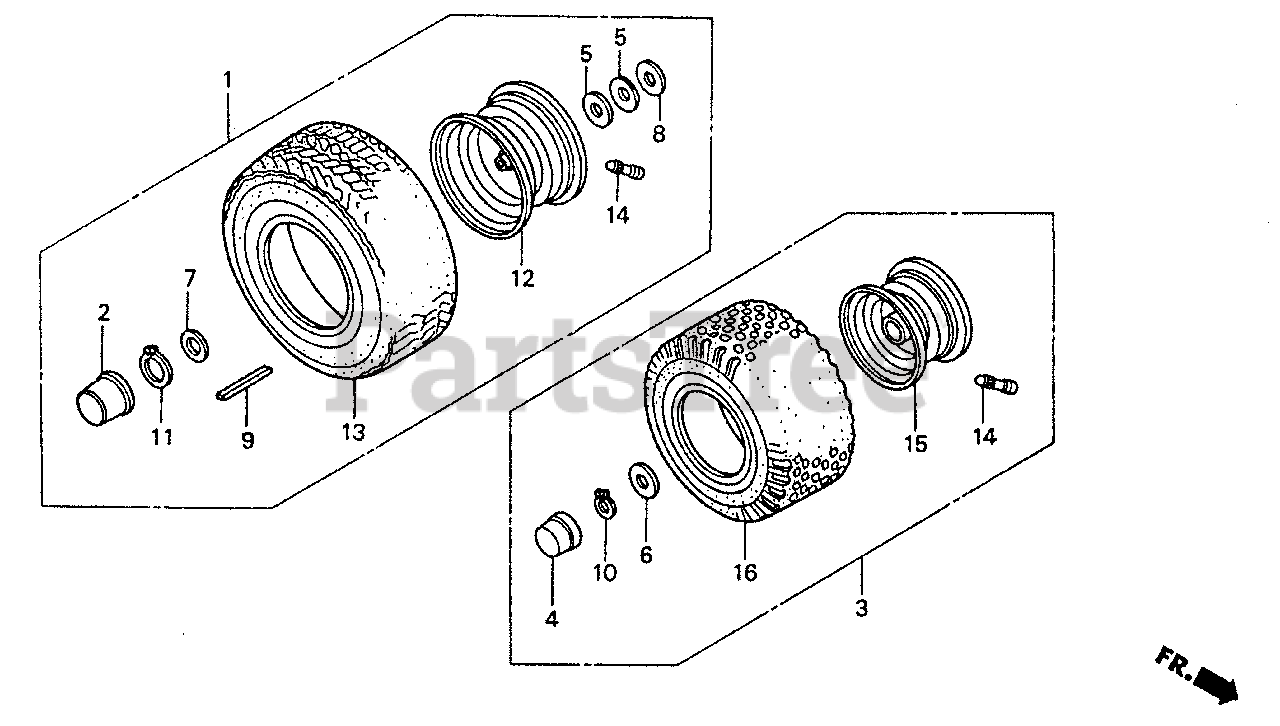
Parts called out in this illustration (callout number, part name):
1	WHEEL ASSY., RR.
2	CAP, RR. WHEEL
3	WHEEL ASSY., FR.
4	CAP, FR. WHEEL
5	WASHER A, WHEEL
6	WASHER, FR. WHEEL
7	WASHER B, WHEEL
8	WASHER, THRUST
9	KEY, RR. WHEEL
10	RING, WHEEL SNAP
11	RING, RR. WHEEL SNAP
12	WHEEL, RR. (AM125708)
13	TIRE, RR.
14	VALVE, SPECIAL (AM30795)
15	WHEEL, FR. (AM125707)
16	TIRE, FR.
